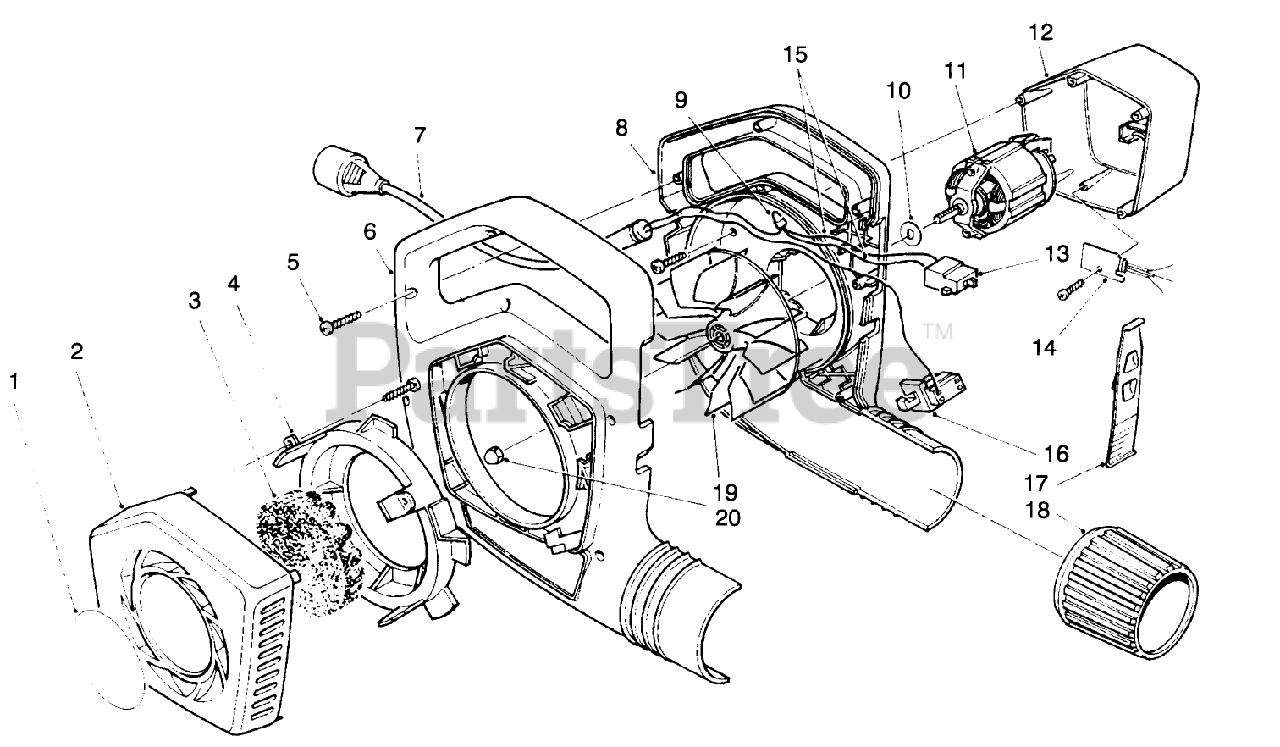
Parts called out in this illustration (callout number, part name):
1	DECAL, COVER
2	INTAKE COVER, 850 BV
3	CENTER FOAM
4	Ring-Coupling
5	Screw
6	Housing-Blower,R.H.
7	POWER SUPPLY CORD 9.5
8	BLOWER HOUSING, LH
9	Connector
10	Washer-Impeller
11	Motor-Blower
12	MOTOR COVER,850 HOTSTAM
13	Switch-2 Speed
14	DIODE ASSEMBLY
15	WIRE, 3 INCH
16	SWITCH-INTERLOCK
17	CAM SWITCH-HOT STAMPED
18	BV-OUTPUT COLLAR
19	IMPELLER, 850 BLOWER
20	NUT-HEX
